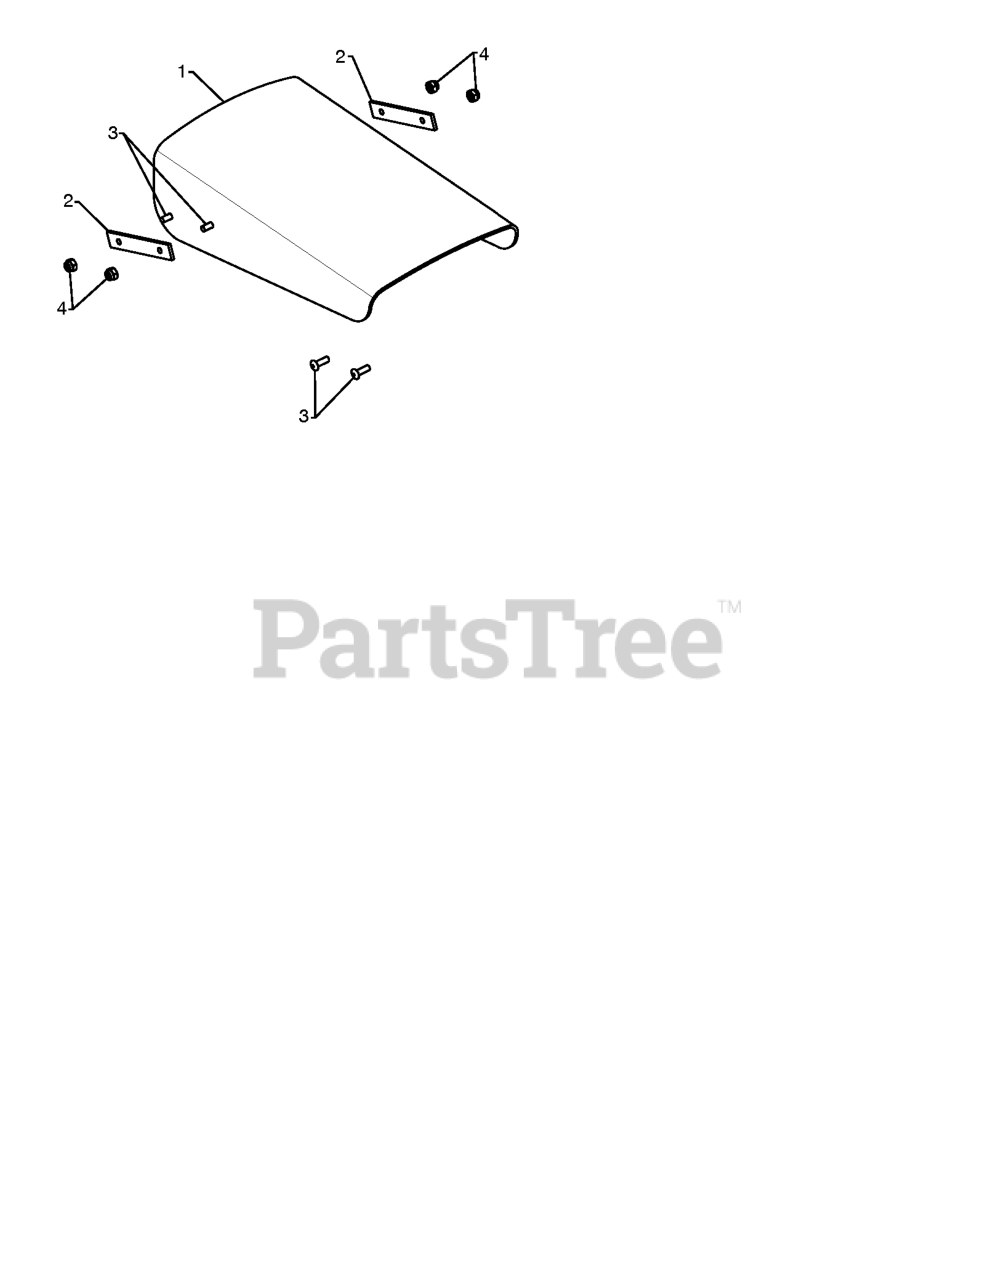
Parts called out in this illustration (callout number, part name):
1	SHIELD.DEFLECTOR.BLACK.SNOW
2	DEFLECTOR SHIELD STRAP
3	SCREW.#8.MACH
4	NUT.HEX.#8
